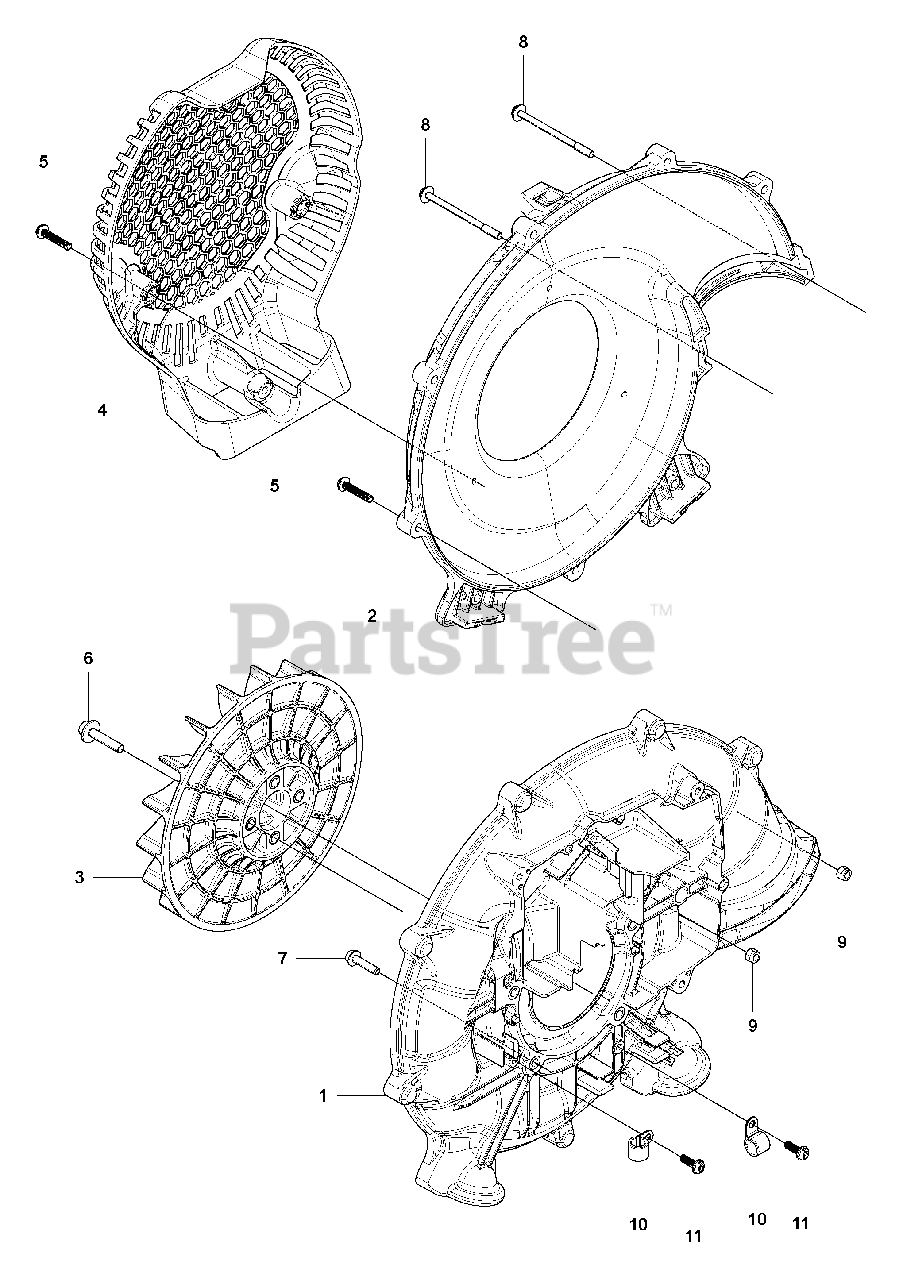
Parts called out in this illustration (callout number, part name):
1	VOLUTE CASE
2	COVER - VOLUTE
5	SCREW
7	BOLT
9	NUT
11	SCREW
